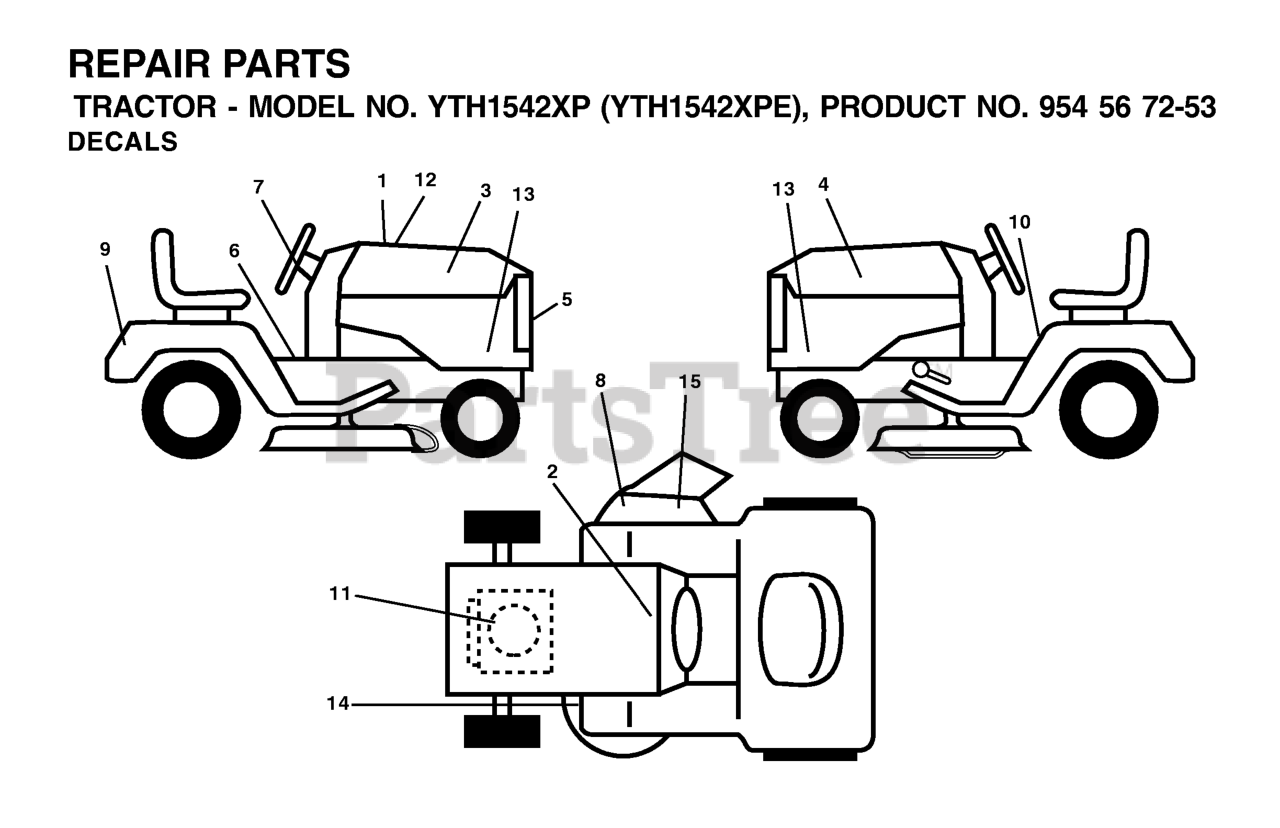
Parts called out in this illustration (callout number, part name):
1	DECAL HOOD CUST. RESP.
2	DECAL BTRY SYMBOLS
5	DECAL.GRILLE.HUSQ
7	DECAL.WHEEL.STEERING.HUSQ.PERM
8	DECAL.WARN.KEEP.HAND.AWAY
9	DECAL, FENDER
10	DECAL FENDER DANGER
13	DECAL HOOD SIDES
14	DECAL V BELT SCHEMATIC
15	DECAL DECK "B" 42"
